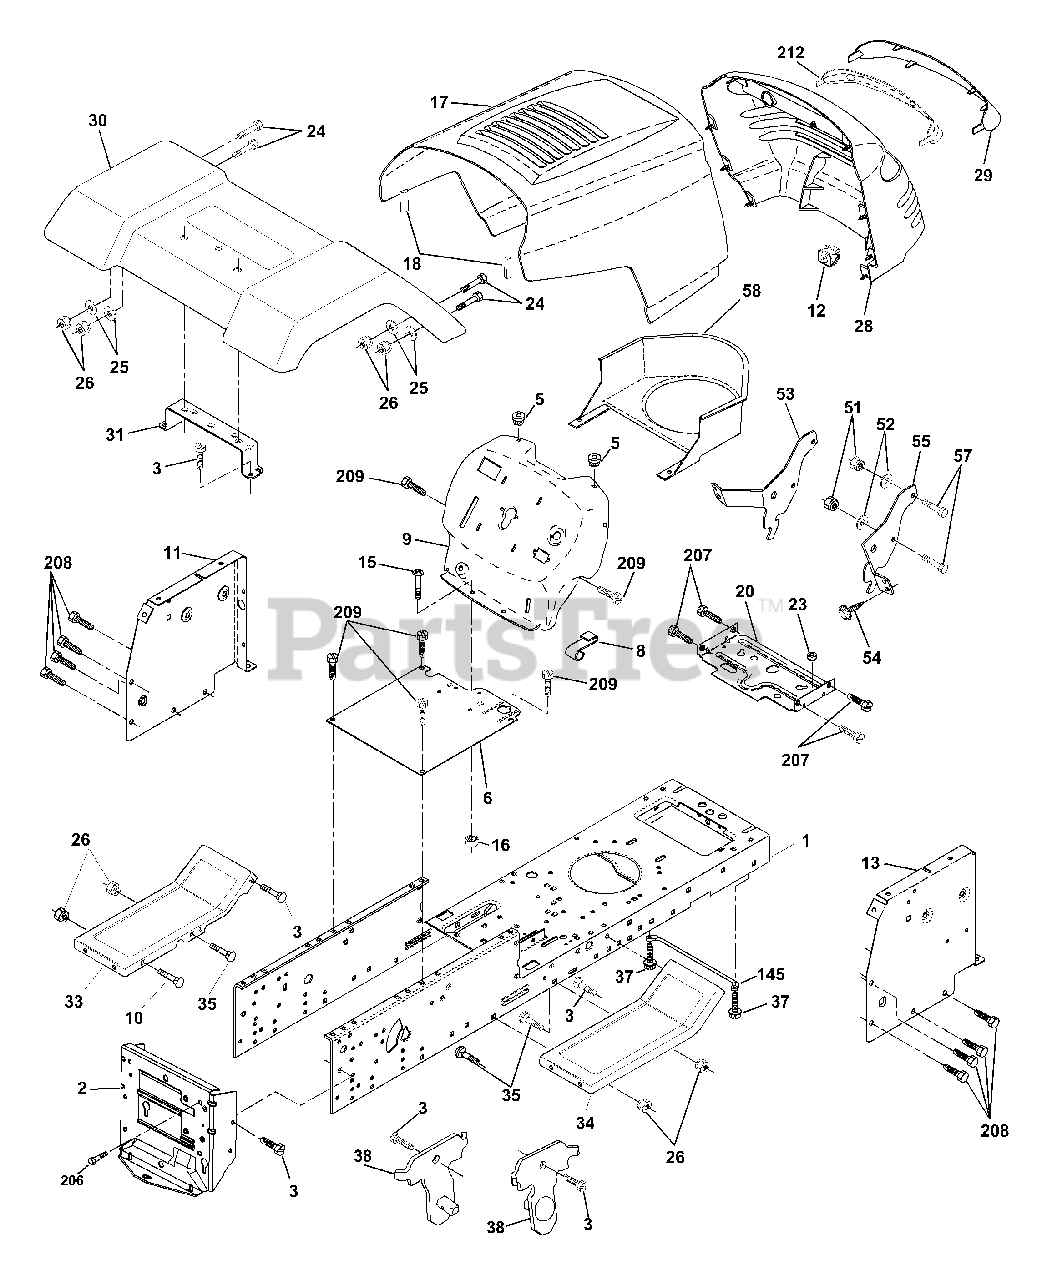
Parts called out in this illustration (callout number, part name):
2	Drawbar
3	Screw 3/8-16 x 3/4
5	Bumper Hood/Dash
6	Saddle Flat Lt Fender Shift
8	Clip Retainer Slide-On
9	Dash
10	Bolt Rd Hd Sqnk. 3/8-16 Unc x 1
11	Panel Asm. Dash Lh
12	Clip Tinnerman Grile P/L
15	Screw Mach Trhd 5/16-18 Unc x 3/4
16	Nut Keps 5/16-18 Unc
17	Hood
18	Bumper Hood
20	Plate Mtg Battery/Fuel Tank Fr
23	Bushing Snap Nyl Blk Fuel Line
24	Bolt Fin Hex 3/8-16 Unc x 1 Gr. 5
25	Washer 13/32 x 13/16 x 12 Ga.
26	Nut Lock Hex w/Insert 3/8-16 UNC
28	Grill/Lens Asm
29	Lens Grille Private label
30	Fender Asm
31	Bracket Fender
33	Footrest Lh
34	Footrest Rh
35	Bolt Rd Hd Sht. Sqnk. 3/8-16 x 3/4
37	Screw Thdrol 5/16-18 x 1/2 Tyt
38	Bracket Asm. Pivot Mower Rear
51	Nut Lock Hex W/Ins. 1/4-20
52	Washer 9/32 x 7/8 x 16 Ga.
53	Bracket Grille LH
54	Screw Hex Wshd 8-18 x 7/8
55	Bracket, Grille RH
57	Bolt Fin Hex 1/4-20 x .75
58	Air Duct Private Label tractor
145	Rod Pivot Chassis/Hood
206	Bolt shoulder 5/16-18
207	Screw Thdrol 5/16-18 x 1/2
208	Screw Thdrol 3/8-16 x 1/2
209	Screw Hex Wsh Thdrol 3/8-16
212	Insert Lens Reflector
